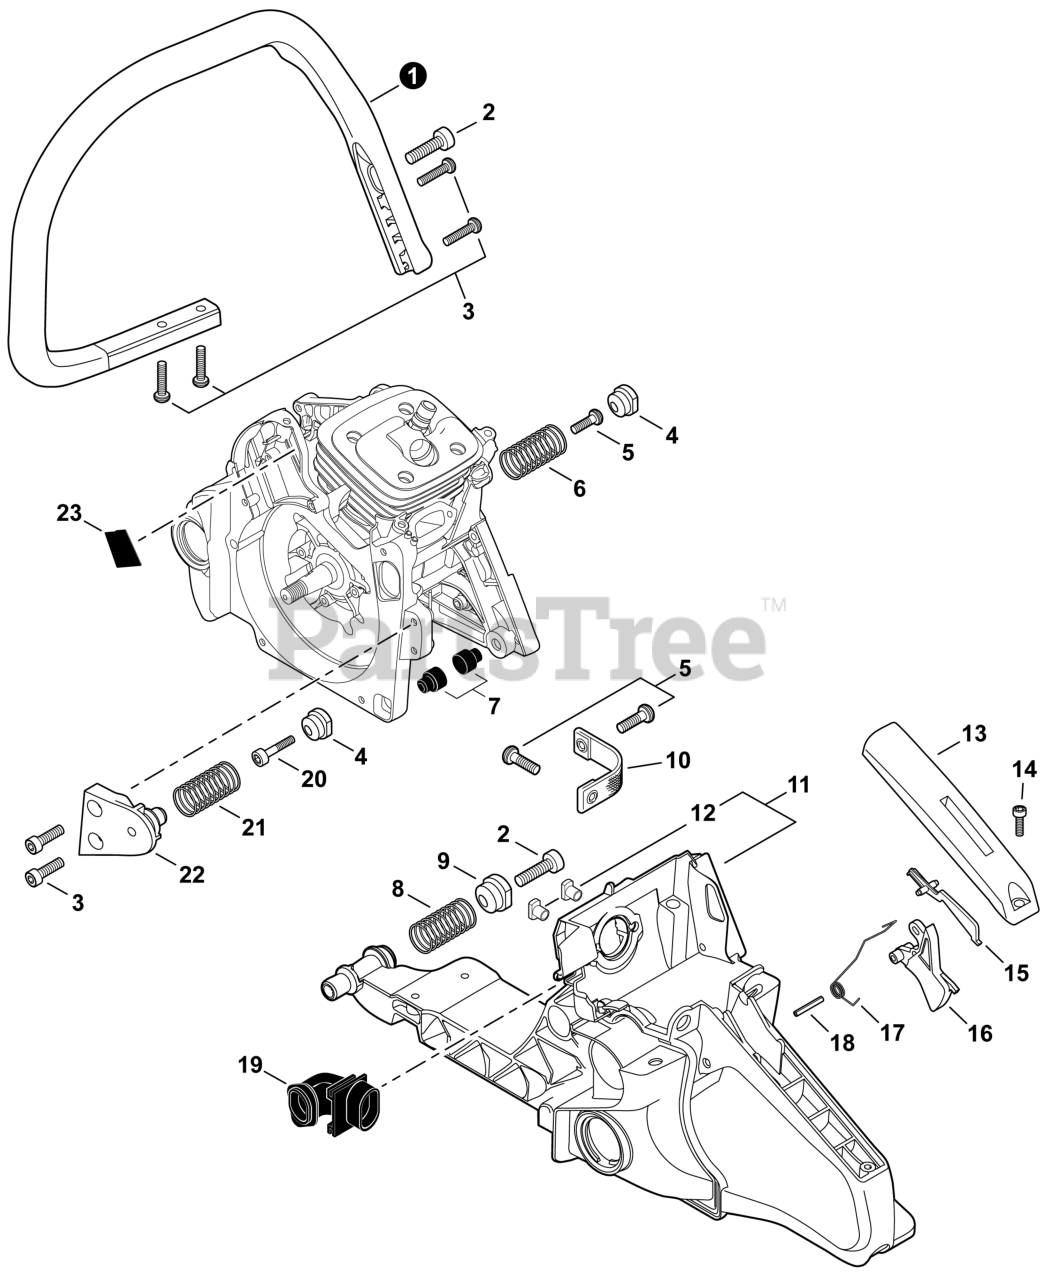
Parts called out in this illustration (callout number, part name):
1	HANDLE, FRONT
2	BOLT, TORX 6x20
3	BOLT, TORX 5x20
4	HOLDER, SPRING 14.4
5	BOLT, TORX 5x16
6	SPRING, COMPRESSION 17x38.4x2.6
7	CUSHION
8	SPRING, COMPRESSION 20x40x3.3
9	HOLDER, SPRING 17
10	STRAP, SAFETY
11	HANDLE, REAR
13	COVER, HANDLE
14	BOLT, TORX 4x12
15	LEVER, THROTTLE LOCKOUT
16	TRIGGER, THROTTLE
17	SPRING, TORSION
18	PIN, SPRING 4x25 SUS
19	PIPE, AIR INTAKE
20	BOLT, TORX 5x25
21	SPRING, COMPRESSION 17x36.7x2.6
22	HOLDER, SPRING
23	CUSHION
